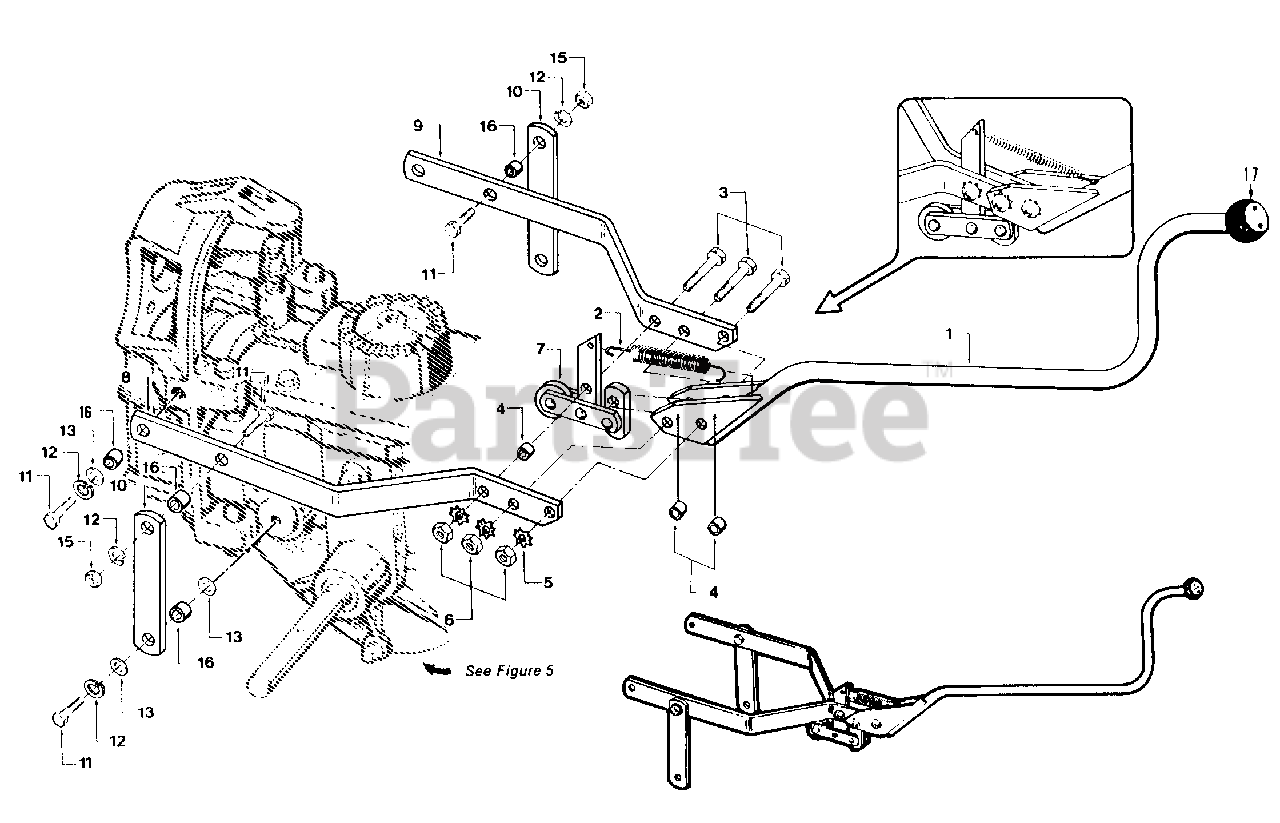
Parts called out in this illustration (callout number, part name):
1	Lever-Wheels/Tines/PTO Drive
2	Spring-clutch pawl
3	Bolt-hex hd., 5/16-18 x 1-1/2"
4	Bushing-3/8"
5	Lockwasher-external tooth, 5/16"
6	Nut-hex, 5/16"-18
7	Roller Assembly
8	Yoke - left side
9	Yoke - right side
10	Link-yoke pivot, left & right, 6-7/8" long
11	Bolt-hex hd., 3/8-16 x 1"
12	Lockwasher-spring lock, 3/8"
13	Washer-flat, 3/8", S.A.E
15	Nut-hex, 3/8"-16
16	Bushing - spacer, 19/64" (.300")
17	Knob-not avail. separately.
